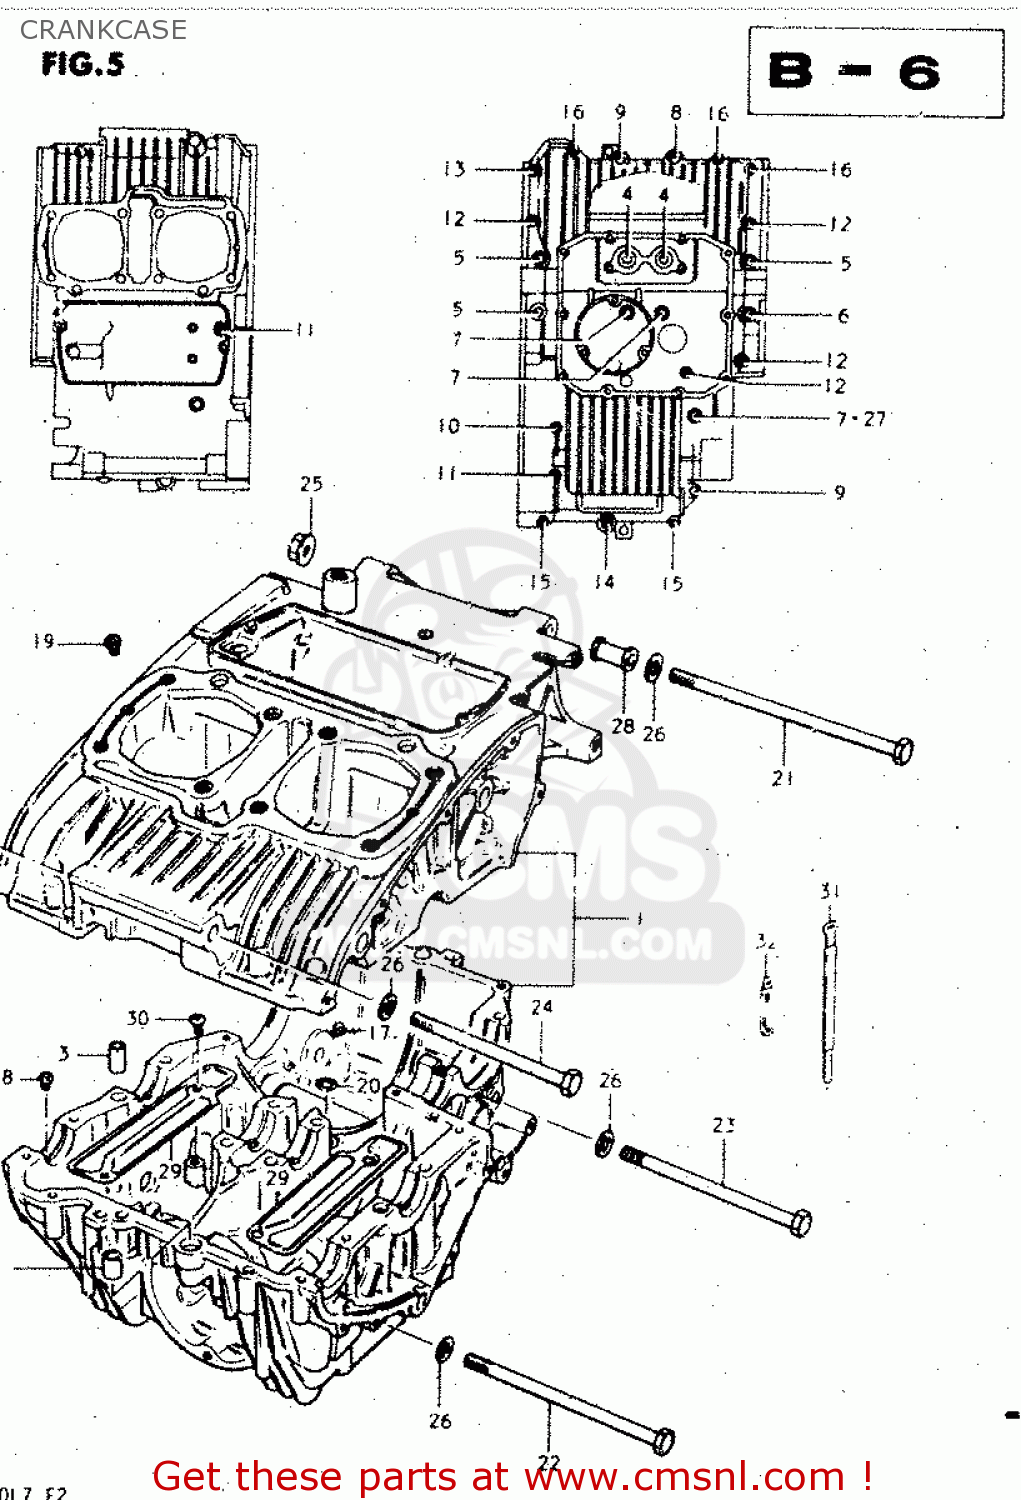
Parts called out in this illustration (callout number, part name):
1	CRANKCASE ASSEMBLY
2	PIN(10.4X13X22)
3	PIN (11X20)(SUS)
4	BOLT
5	BOLT
6	BOLT
7	BOLT
8	BOLT 8X65
9	BOLT (8X45)
10	BOLT
11	BOLT
12	BOLT (6X90)
13	BOLT (6X70)
14	BOLT 6X65
15	BOLT ,6X50
16	BOLT,UNDER
17	JET
18	JET
19	JET
20	O RING(D:1.05,ID:3.1)
21	BOLT 10X250
22	BOLT
23	BOLT 10X160
24	BOLT
25	NUT 10MM
26	WASHER
27	GASKET 8.2X14X1 (NAS)
28	SPACER,ENGINE MOUNT
29	PLATE,OIL SEPARATOR
30	SCREW
31	CLAMP
32	CLAMP
